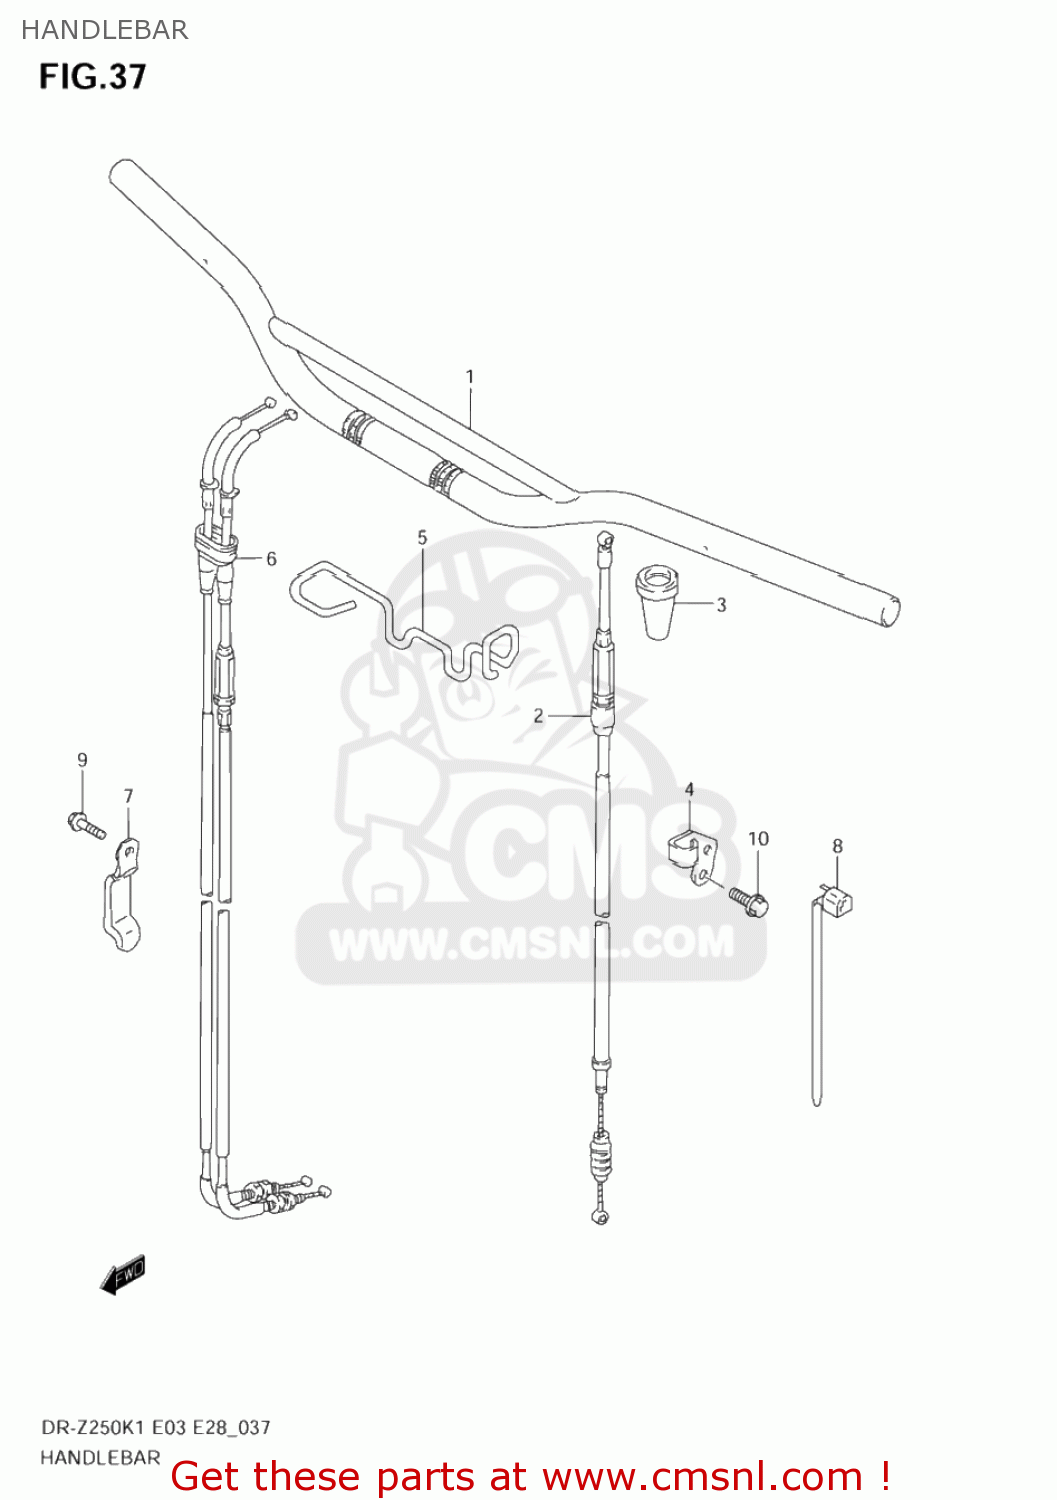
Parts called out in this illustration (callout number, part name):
1	HANDLEBAR(SILVER)
2	CABLE ASSY,CLUTCH
3	BOOT,CLUTCH CABLE
4	STOPPER,CLUTCH CABLE
5	GUIDE,CABLE
6	CABLE ASSY,THROTTLE
7	CLAMP
8	CLAMP(L:165)
9	BOLT
10	BOLT
